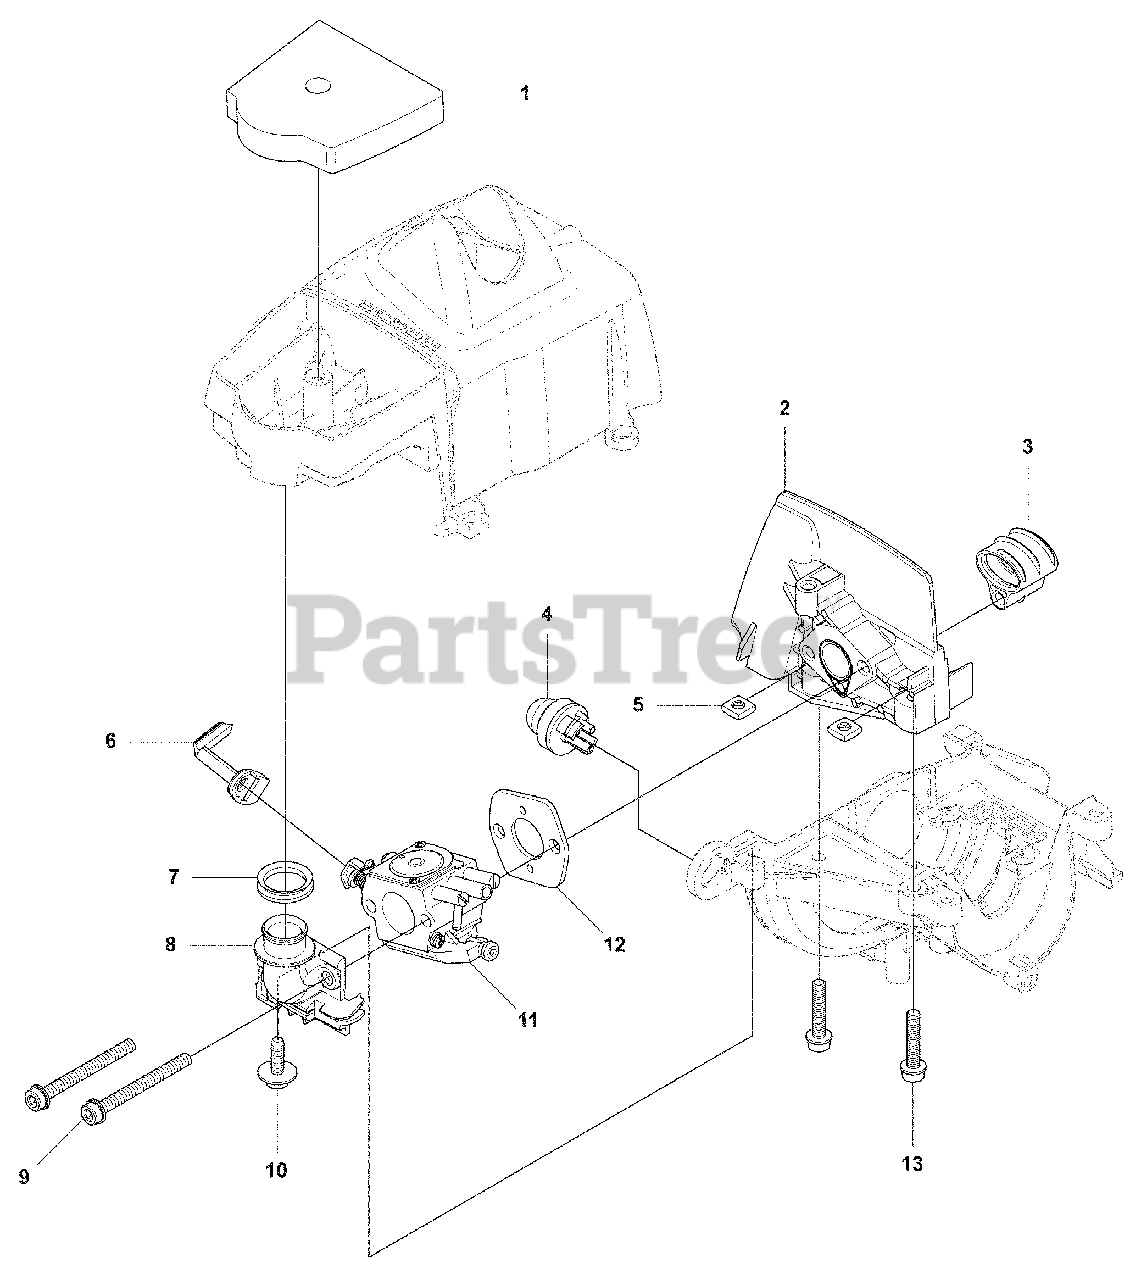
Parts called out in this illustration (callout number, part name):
1	Air Filter
4	Air Purge Bulb
5	Square Nut
6	Choke Control Lever
11	Carburetor Kit
12	Carburetor Gasket
